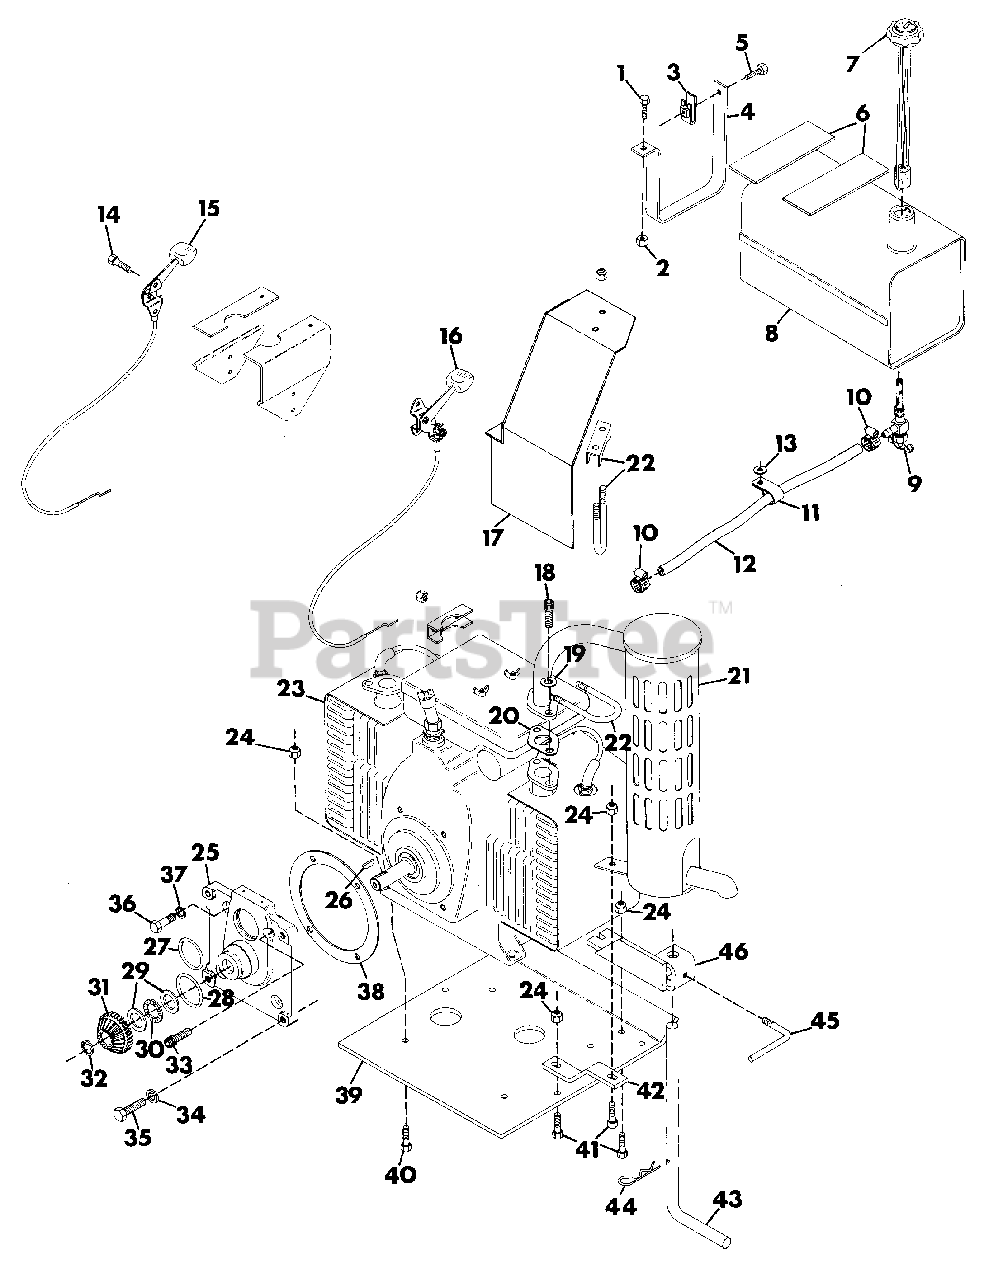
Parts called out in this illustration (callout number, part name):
1	BOLT, HEX 5/16-18X1.25
2	NUT, LOCK 5/16-18
3	NUT, RETAINER
4	STRAP, GAS TANK
5	BOLT, HEX 5/16-18X.75
6	PAD, GAS TANK
7	GAUGE, FUEL
8	TANK, FUEL
9	VALVE AND STRAINER
10	CLAMP, HOSE
11	CLAMP, NYLON
12	LINE, FUEL
13	WASHER, FLAT .344X.688X.065
14	SCREW, TAPPING 10-24X.50
15	LEVER, CONTROL
16	LEVER, CONTROL
17	SHIELD, HEAT L.H.
17	SHIELD, HEAT R.H.
18	SCREW, CAP 5/16-18X.75
19	WASHER, LOCK 5/16 REG.
20	GASKET, EXHAUST
21	MUFFLER, PRO MASTER-60 KT 17
22	CLAMP, MUFFLER
23	ENGINE, 17 HP KOHLER
23	ENGINE, 19 HP KOHLER
24	NUT, LOCK 3/8-16
25	ADAPTOR, ENGINE
26	KEY, SQUARE .250X1.250
27	O-RING, 2.50X2.750X.125
28	O-RING, 3.000X3.188X.094
29	RACE, BEARING THRUST
30	BEARING, THRUST
31	GEAR, SPUR AND BEVEL INPUT
32	RING, RETAINING 1.125 SHAFT
33	SCREW, CAP 7/16-14X1.00
34	WASHER, LOCK 1/2 REG.
35	BOLT, HEX 1/2-13X1.25
36	BOLT, HEX 7/16-14X1.125
37	WASHER, LOCK 7/16 SP HEAVY
38	GASKET, ENGINE
39	PLATE, SKID
40	BOLT, HEX 3/8-16X1.25
41	BOLT, HEX 3/8-16X1.12
42	BRACKET, MUFFLER
43	STAND, KICK
44	PIN, HAIR
45	HANDLE, ADJUSTING
46	STAND, SUPPORT
